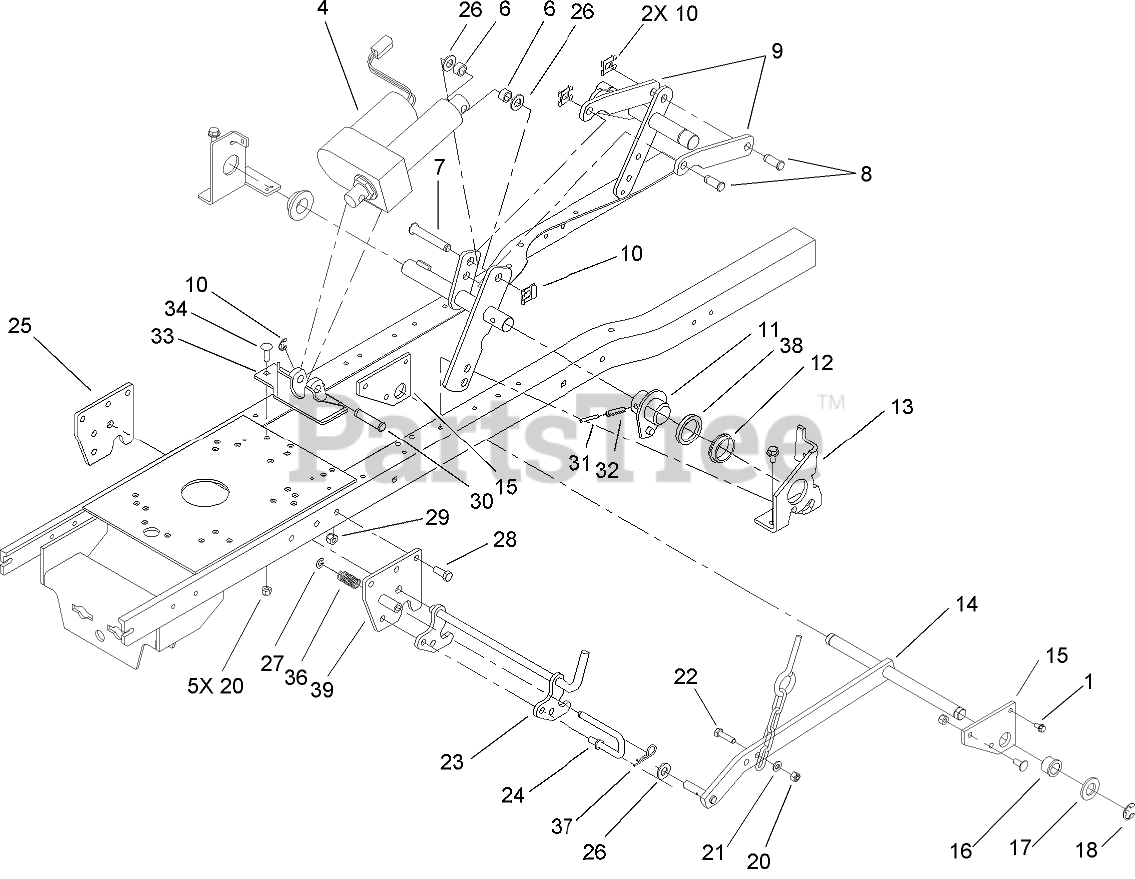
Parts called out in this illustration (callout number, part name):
1	SCREW-HWHTF
4	ACTUATOR
6	SPACER
7	PIN-CLEVIS
8	PIN-CLEVIS
9	STRAP-LINK, LIFT
10	CLIP-PIN
11	END CAP ASM
12	BUSHING
13	BRACKET-ARM, LIFT
14	LIFT BAR ASM
15	Plate-Lift, Rear
16	BUSHING-FLANGE
17	WASHER-FLAT
18	E-RING
20	NUT-LOCK, NI
21	WASHER-PLAIN
22	SCREW-HH
23	MIDHITCH LATCH ASM
24	ROD-CATCH
25	Plate-Hitch
26	WASHER-FLAT
27	RING-RETAINING
28	SCREW-HH
29	NUT-LOCK, NI
30	PIN-CLEVIS
31	PIN-SPRING
32	PIN-ROLL
33	ACTUATOR BRACKET ASM
34	SCREW-CARR
36	SPRING-COMPRESSION
37	PIN-HAIR
38	SPACER
39	MIDHITCH ASM
